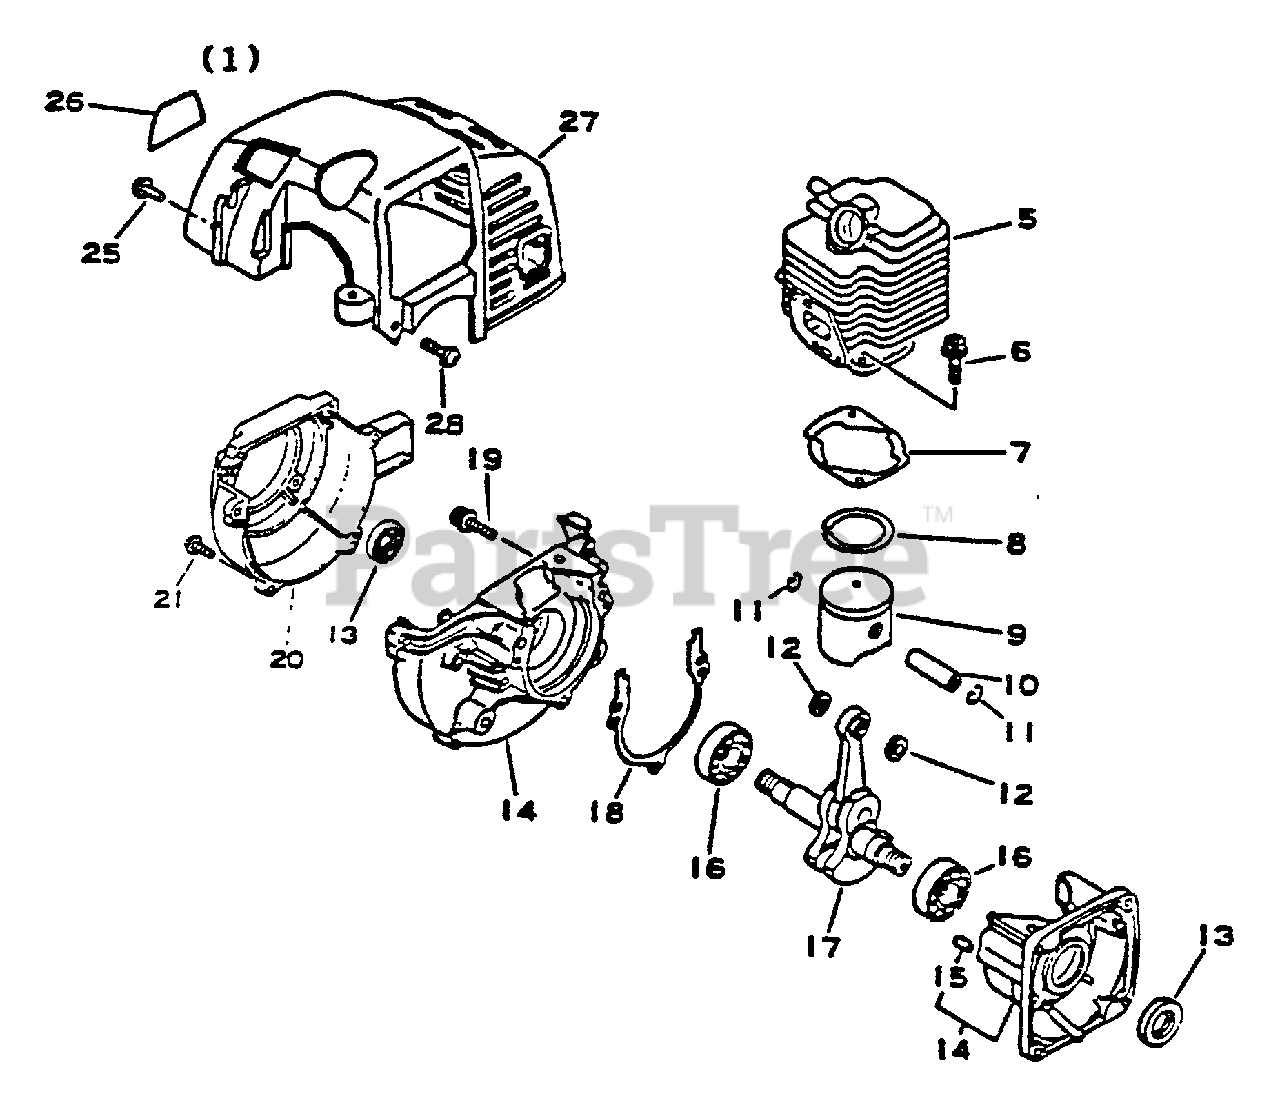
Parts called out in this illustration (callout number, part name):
5	CYLINDER
6	SCREW - 5X22
7	GASKET, CYLINDER
8	RING, PISTON
9	PISTON
10	PIN, PISTON
11	RING, RETAINING
12	SPACER, PISTON
13	SEAL, OIL
14	CRANKCASE KIT
15	PIN - LOCATING
16	BEARING, BALL - 6201
17	CRANKSHAFT ASSY
18	GASKET, CRANKCASE
19	SCREW - 5X25
20	CASE, FAN - ORANGE
21	SCREW - 4X16
25	SCREW - 4X12
27	COVER, ENGINE
28	SCREW - 4X16
